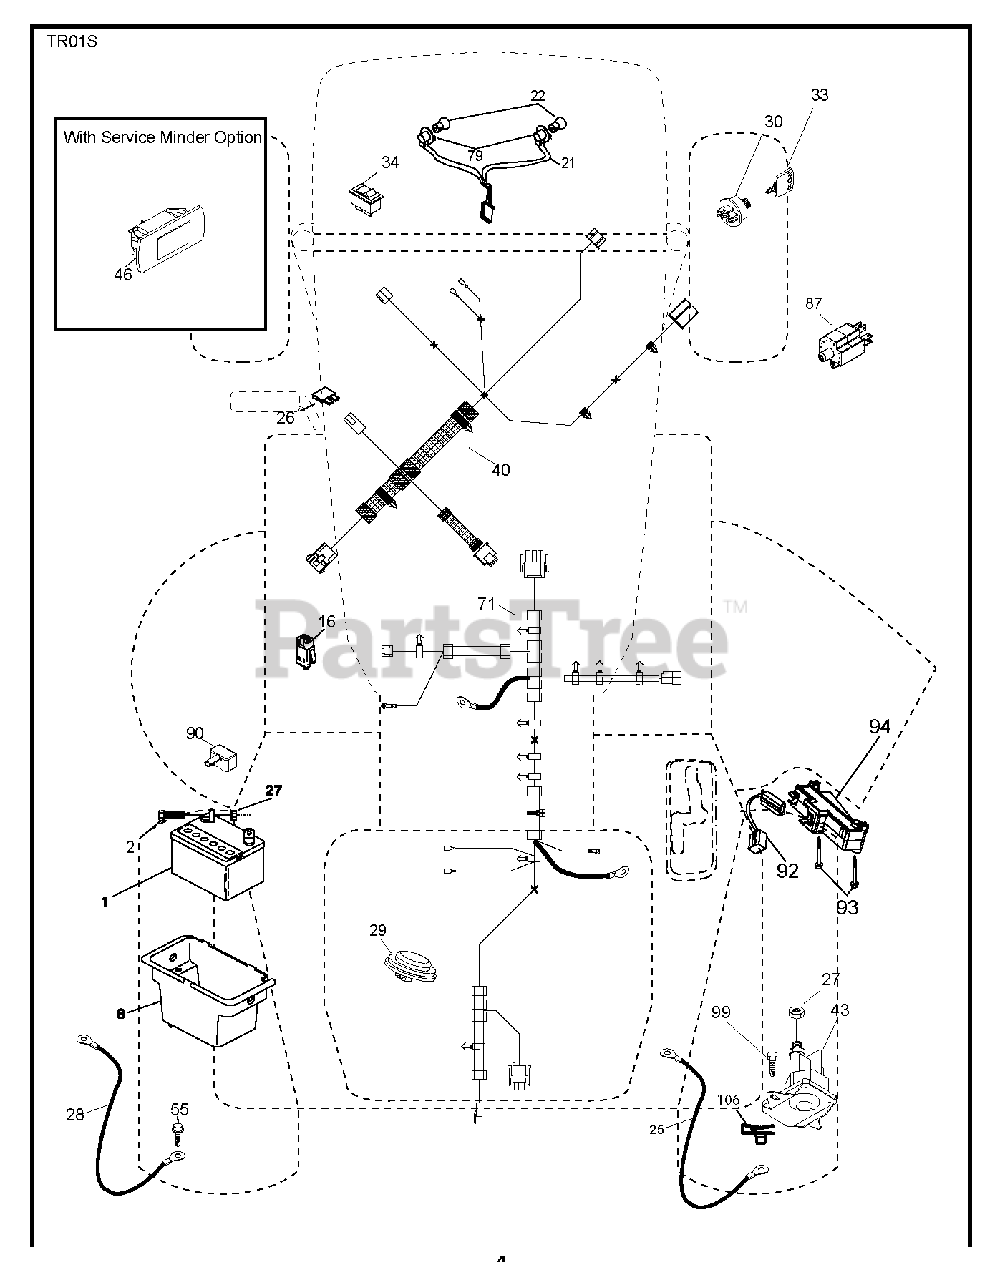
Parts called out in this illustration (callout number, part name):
1	Battery, Dry 30 Amp
2	BOLT.HEX.1/4.X.3/4.DICHROMATE
8	BOX.BATTERY.MNT.REAR.L
16	SWITCH INTERLOOK PUSH-IN
21	HARNESS.LIGHT W/4152J BULBS
25	CABLE.BATT.RED.8GA.17
26	FUSE 20AMP
27	NUT
28	CABLE.GROUND.REAR.BATTERY.8G
29	SWITCH.SEAT.DELTA.OPC.
30	SWITCH.IGN.DELTA.W.LGH.ROS
33	KEY.CHAIN.BLISTER.PACK.GEN.USA
40	HARNESS.TEX.DASH.MAN.REAR BATT
43	SOLENOID.W/BRASS.PLUNGER
46	RP GUAGE.SRVCMNDR.HRMTR.
55	SCREW 5/16"
71	HARNESS.TEX.CHSSIS.REAR.BATT
79	BULB HOLDER ASM.
87	SWITCH.INTRLCK.CLUTCH.
90	COVER.TERMINAL.BATTERY
92	HARNESS.PIGTAIL.CONSLE
93	SCREW.PLASTITE
94	MODULE.REVERSE.ROS
99	SCREW HEXWSHR 1/4-20X3/4
106	1/4-20 U NUT
